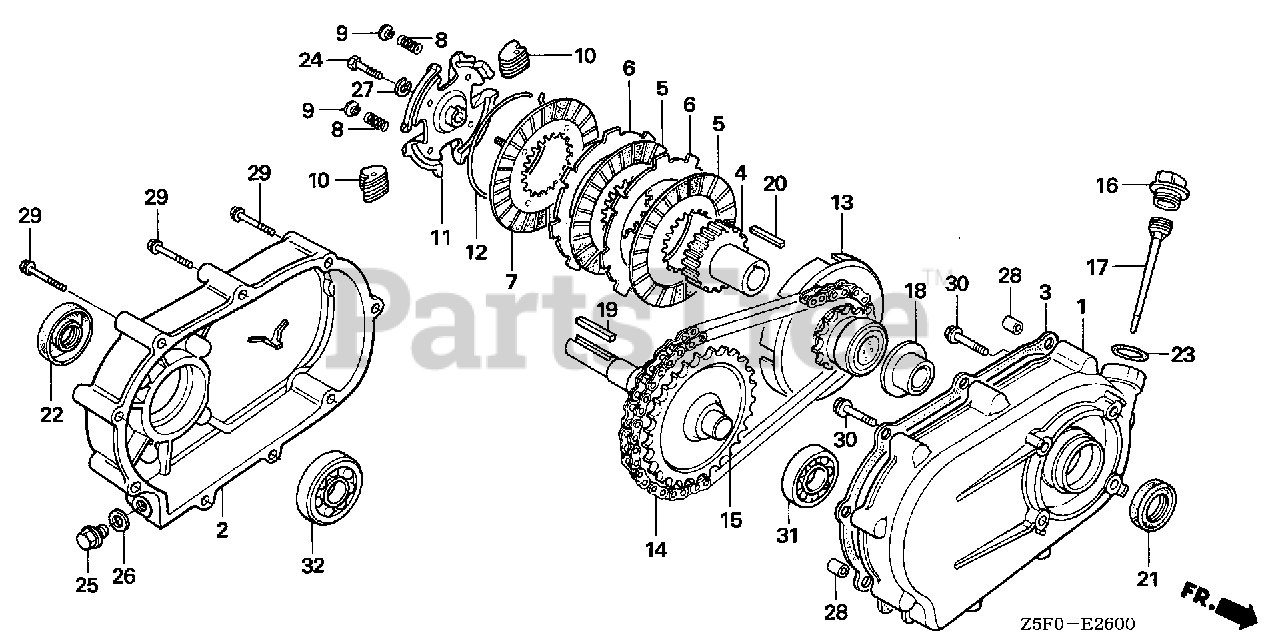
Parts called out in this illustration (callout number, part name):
1	CASE, REDUCTION
2	COVER, REDUCTION
3	GASKET, REDUCTION COVER
4	CENTER, CLUTCH
5	DISK, CLUTCH FRICTION
6	PLATE, CLUTCH
7	PLATE, CLUTCH PRESSURE
8	SPRING, CLUTCH FREE
9	HOLDER, CLUTCH SPRING
10	WEIGHT, CLUTCH
11	HOLDER, CLUTCH WEIGHT
12	CENTER, CLUTCH WEIGHT
13	SPROCKET, DRIVE (14T)
14	CHAIN, DRIVE (RK428SH-36LE)
15	SHAFT, P.T.O. (28T)
16	CAP, REDUCTION OIL (GRAY)
17	DIPSTICK, OIL
18	WASHER, THRUST (25MM)
19	KEY (7X7X33)
20	KEY, CLUTCH CENTER
21	OIL SEAL (30X46X8)
22	OIL SEAL (30X50X7)
22	OIL SEAL (PJ30507)
23	O-RING (26X2.7)
24	BOLT, HEX. (8X35)
25	BOLT, DRAIN PLUG (12MM)
26	WASHER, DRAIN PLUG (12MM)
27	WASHER, SPRING (8MM)
28	PIN A, DOWEL (8X14)
29	BOLT, FLANGE (6X50)
30	BOLT, FLANGE (8X32)
31	BEARING, RADIAL BALL (6205)
32	BEARING, RADIAL BALL (6206)
